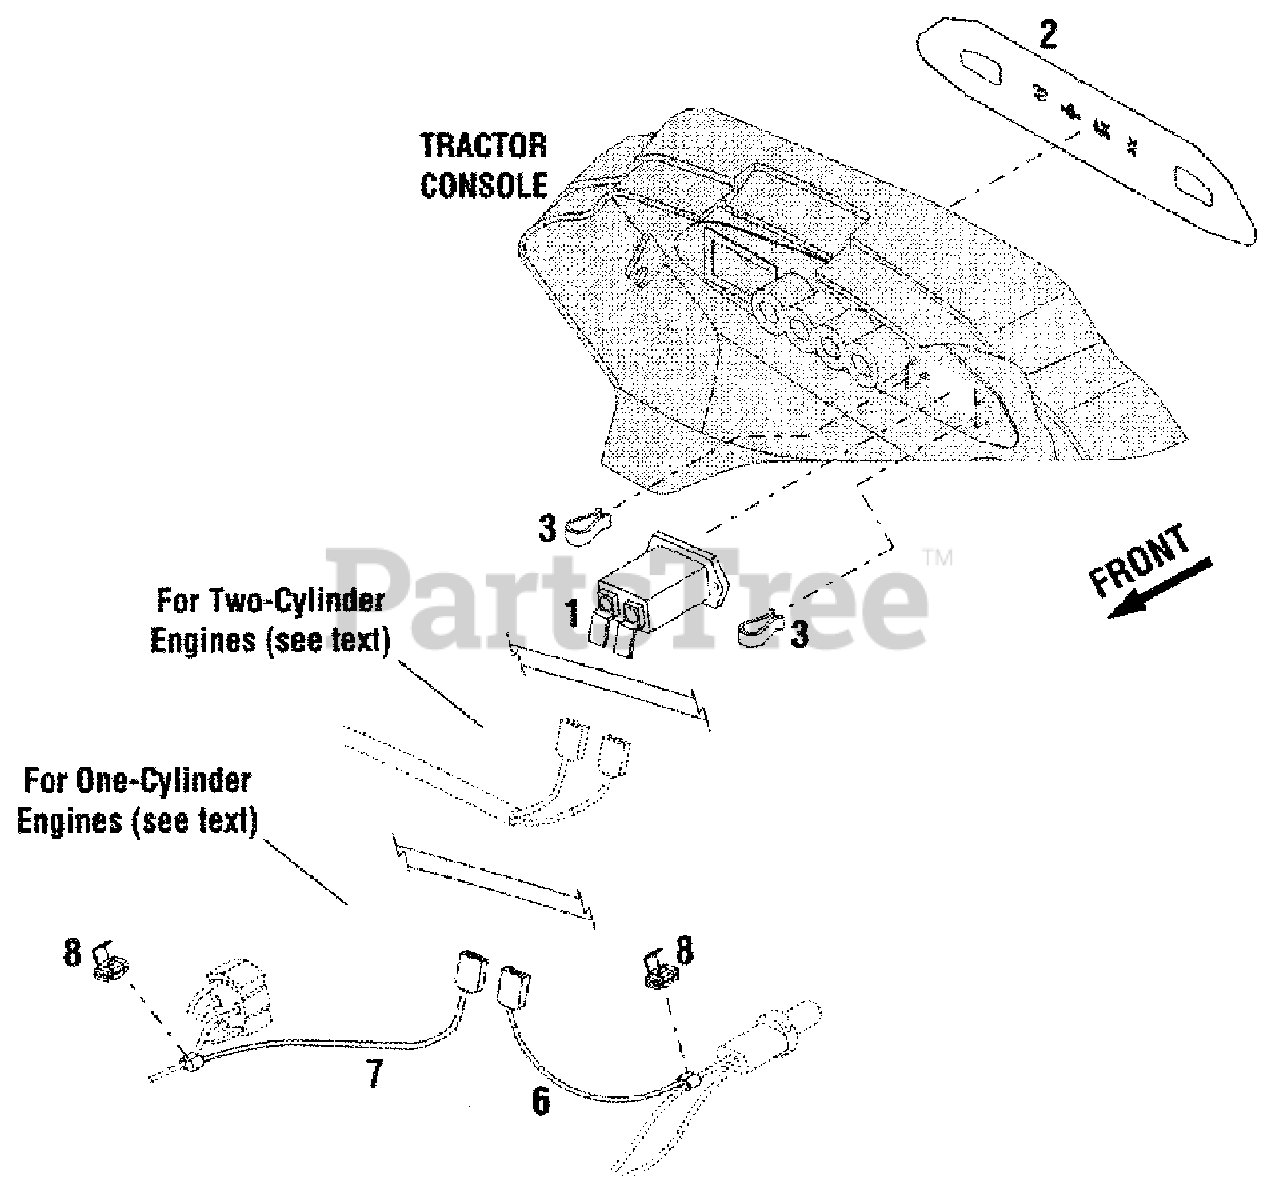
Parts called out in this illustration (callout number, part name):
1	Hour Meter
2	Lens (Warning Lights)
3	Tinnerman Clip
6	Black Wire Lead Assembly
7	Red Wire Lead Assembly
8	Splice Connector
